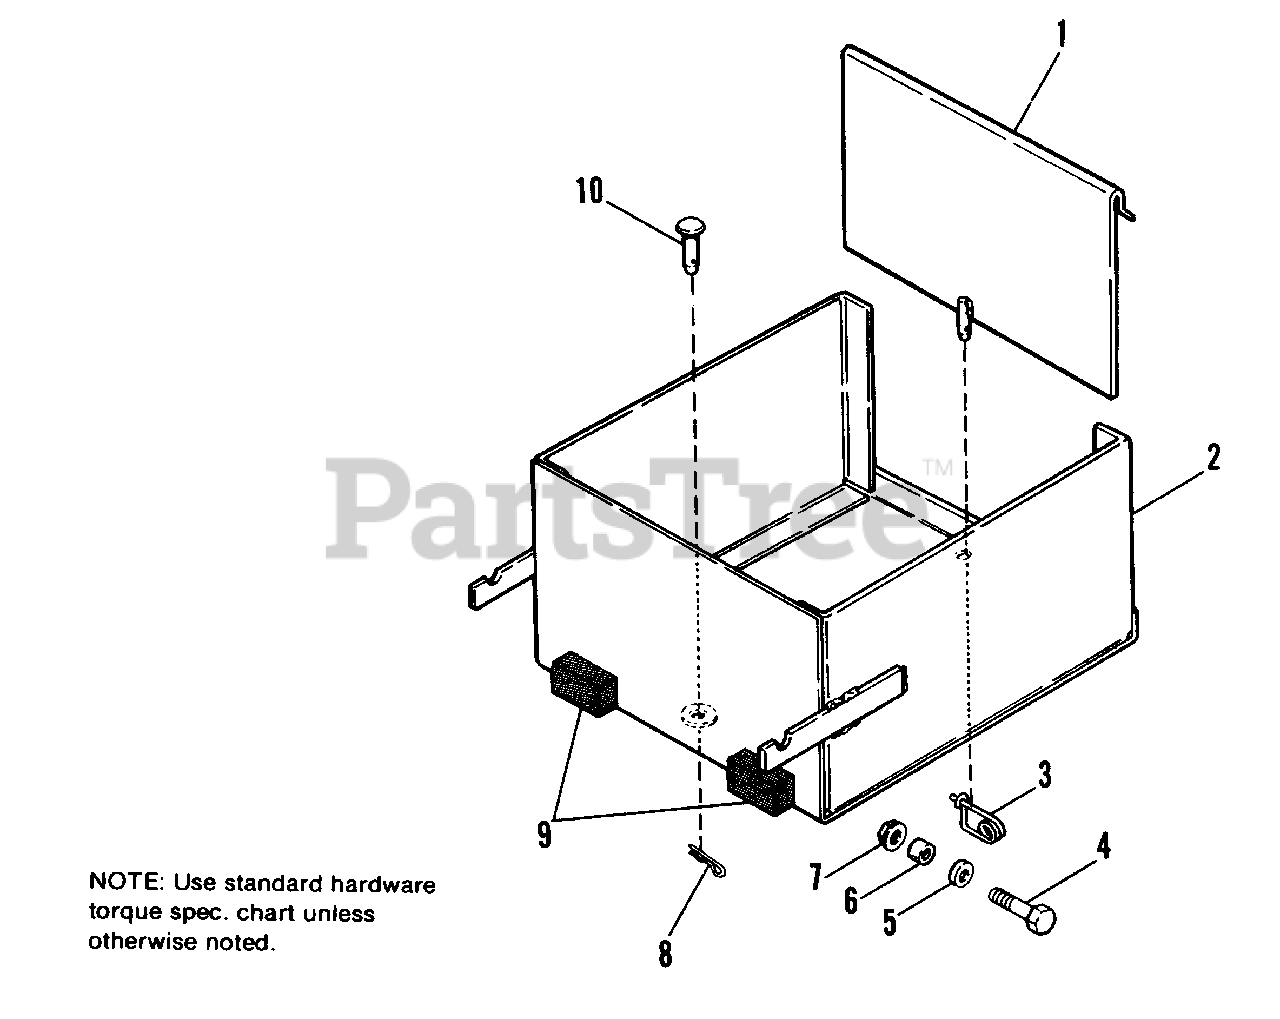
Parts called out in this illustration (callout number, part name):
3	SAFETY CLIP
4	CAPSCREW, 3/8-16 x 1-1/4
5	WASHER
7	NUT, Whizlock, 3/8-16
9	FOAM PADS (Mfg. No. 1691838 Only)
